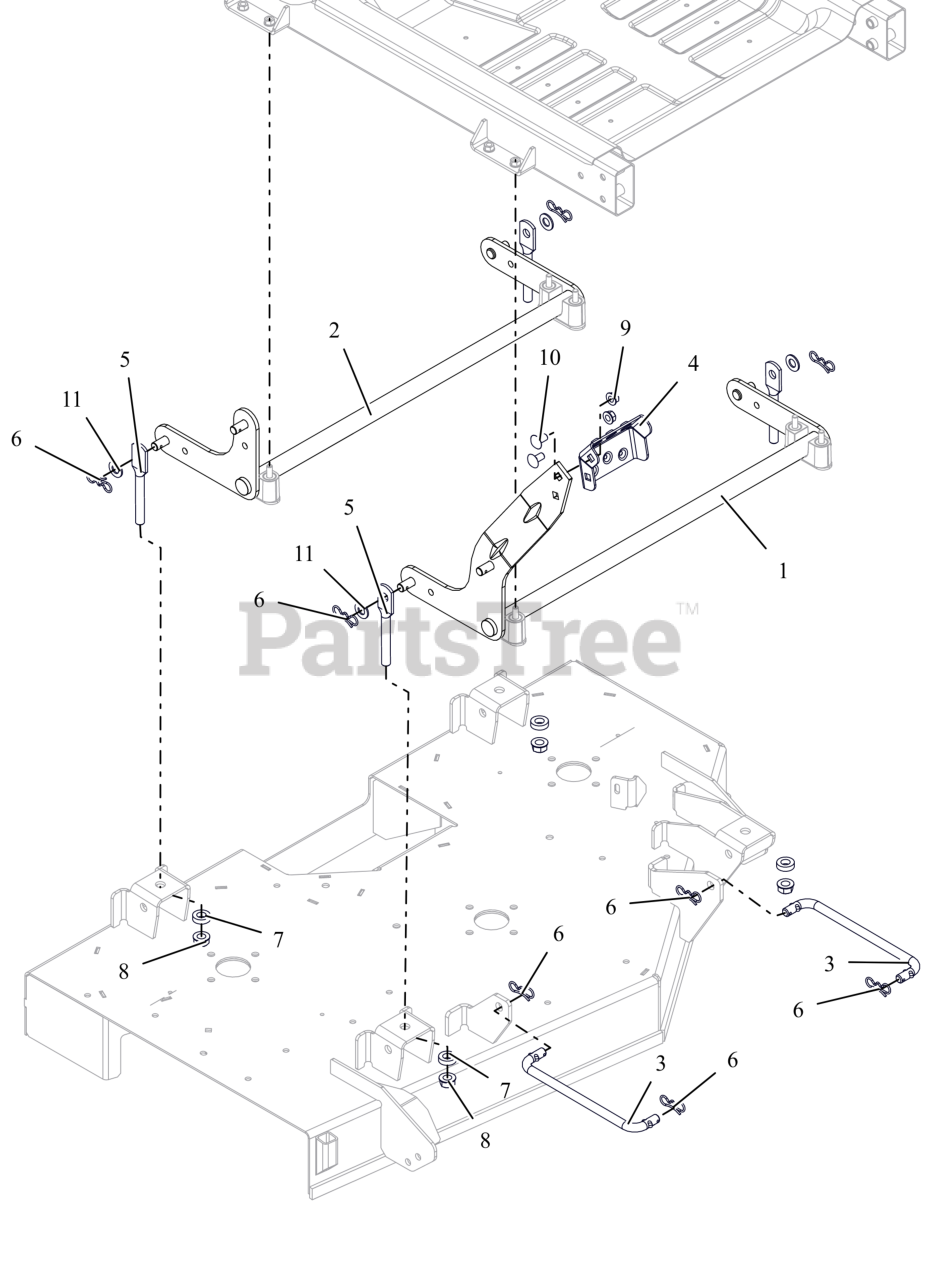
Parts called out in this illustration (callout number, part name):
1	WLDMT, FRONT DECK LIFT PIVOT
2	WLDMT, REAR DECK PIVOT
3	LINK, DRAG
4	PEDAL, DECK LIFT (BOLT ON)
5	LINK,DECK (HOLE-LONG)
6	PIN, BOWTIE .091X1.875 ZCC
7	WASHER, RUBBER
8	NUT-LK-CTR-FLG .500-13 GG ZCC
9	NUT-LK-CTR-FLG .375-16 GF ZCC
10	BTL,RHSSN .375-16 X 0.75 G5 FPB
11	WSHR-FL-NYL .518X1.000X.080
